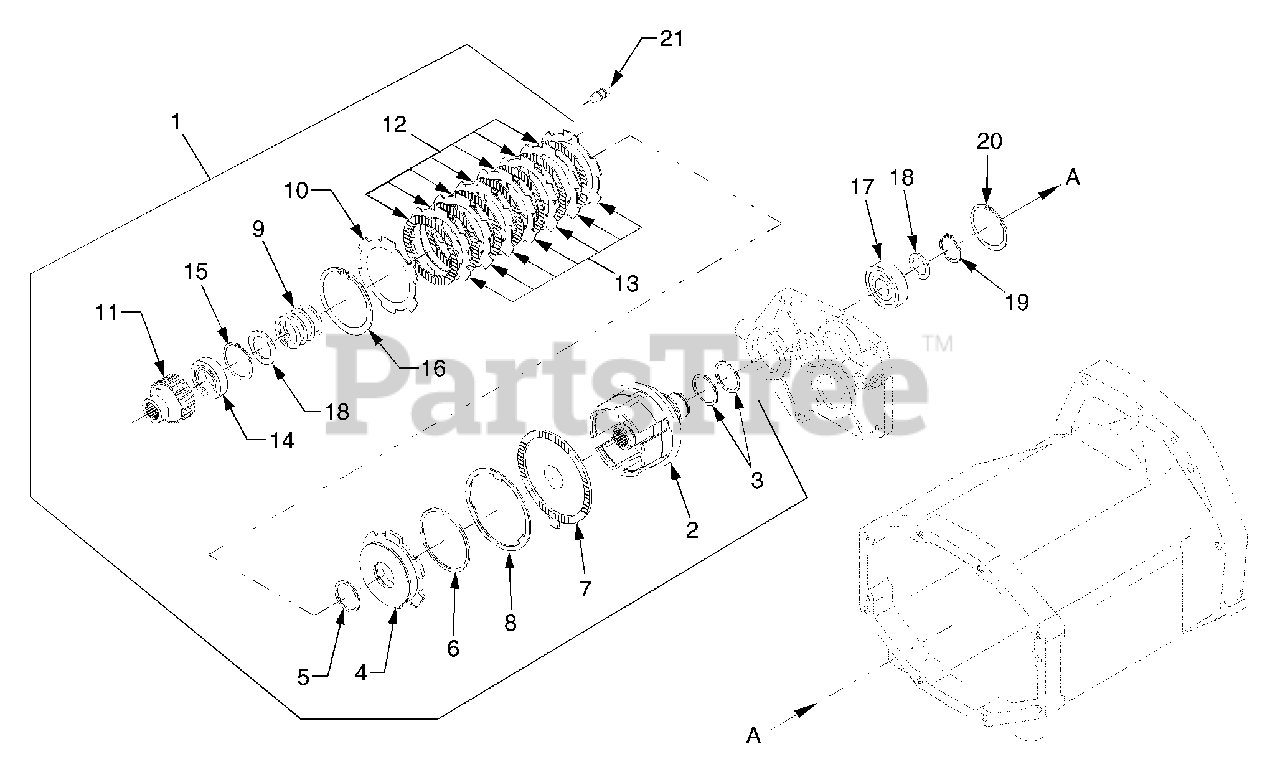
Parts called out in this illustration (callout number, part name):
1	PTO Clutch Ass'y,
6	Ring, Piston
8	Plate, Return
10	Plate, Pressure
13	Plate, Clutch
14	Bearing, Ball
17	Bearing, Ball
